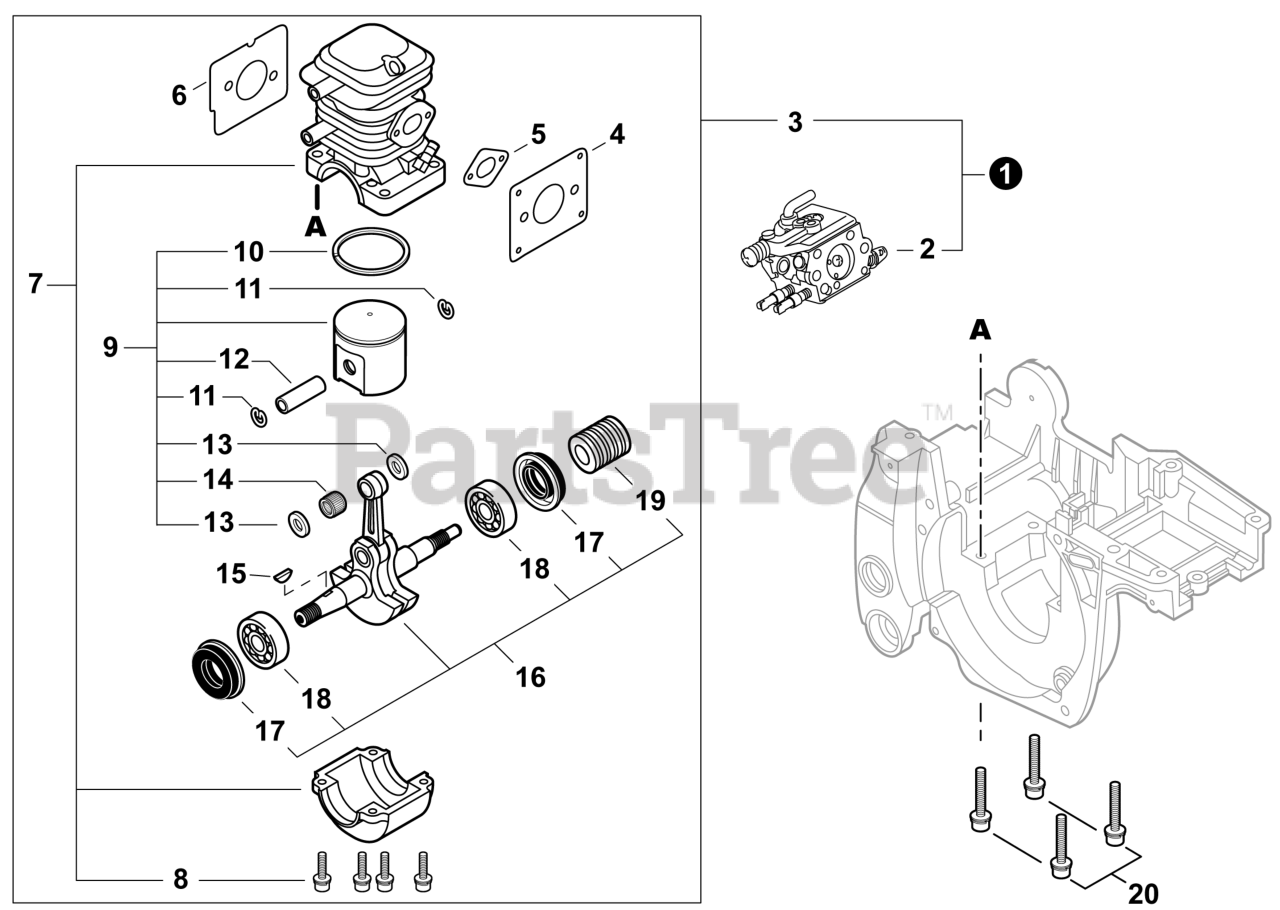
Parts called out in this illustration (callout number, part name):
1	SHORT BLOCK AND CARBURETOR WT-985
2	CARBURETOR WT-985
3	SHORT BLOCK
4	GASKET, INTAKE
5	GASKET, INTAKE
6	GASKET, EXHAUST
7	CRANKCASE KIT
8	BOLT 5×22
9	PISTON KIT
10	RING, PISTON
11	RING, SNAP
12	PIN, PISTON
13	WASHER, THRUST
14	BEARING, NEEDLE 9
15	KEY, WOODRUFF
16	CRANKSHAFT ASSY
17	SEAL, OIL 12
18	BEARING, BALL 6201
19	GEAR, WORM
20	BOLT 5×30
